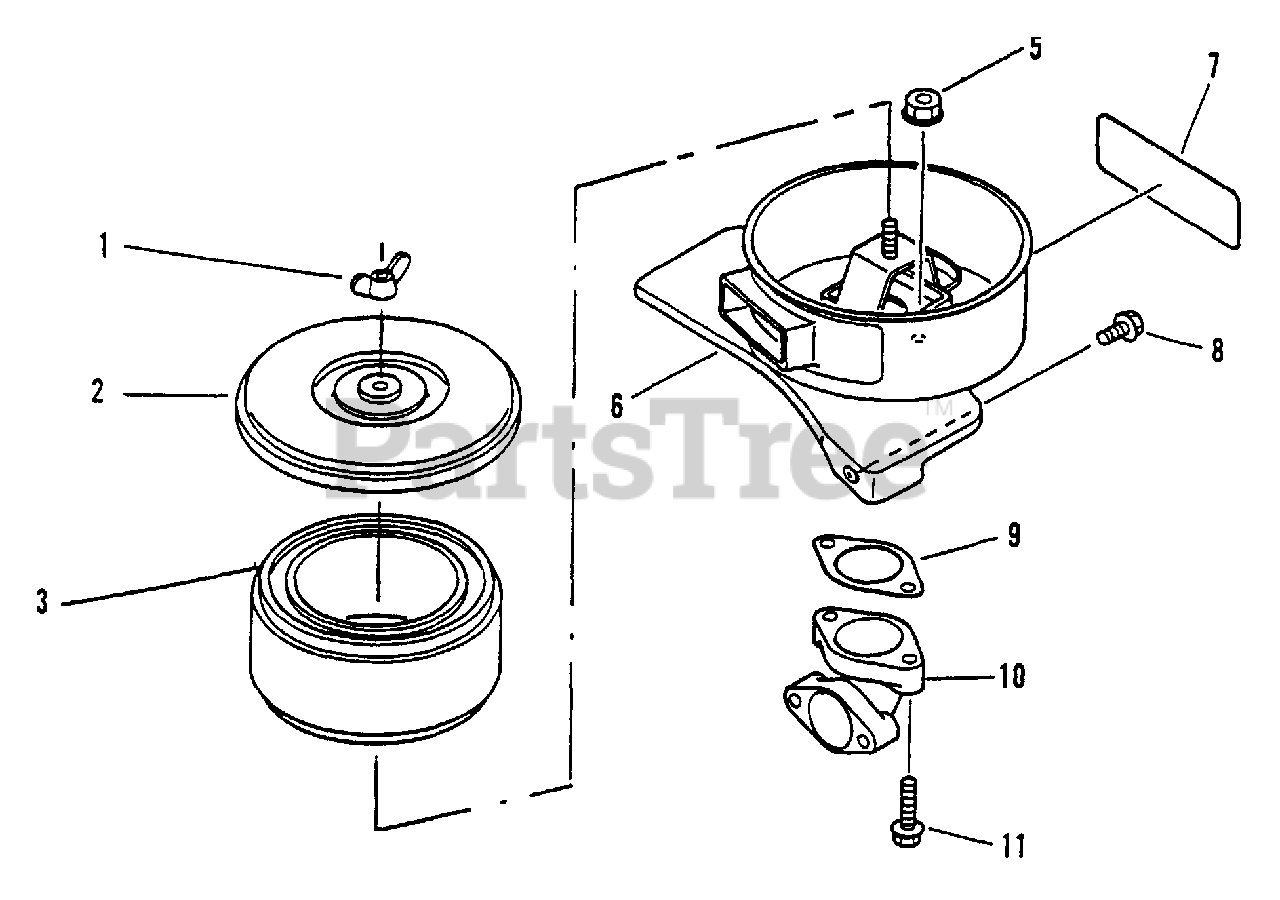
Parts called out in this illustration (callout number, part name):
1	NUT, WING
2	COVER, AIR FILTER
3	FILTER, AIR
5	NUT, FLANGE M6
6	CASE, AIR FILTER
7	LABEL - CAUTION
8	SCREW - 6×10
9	GASKET, INTAKE
10	MANIFOLD, INTAKE
11	BOLT - 6×25
